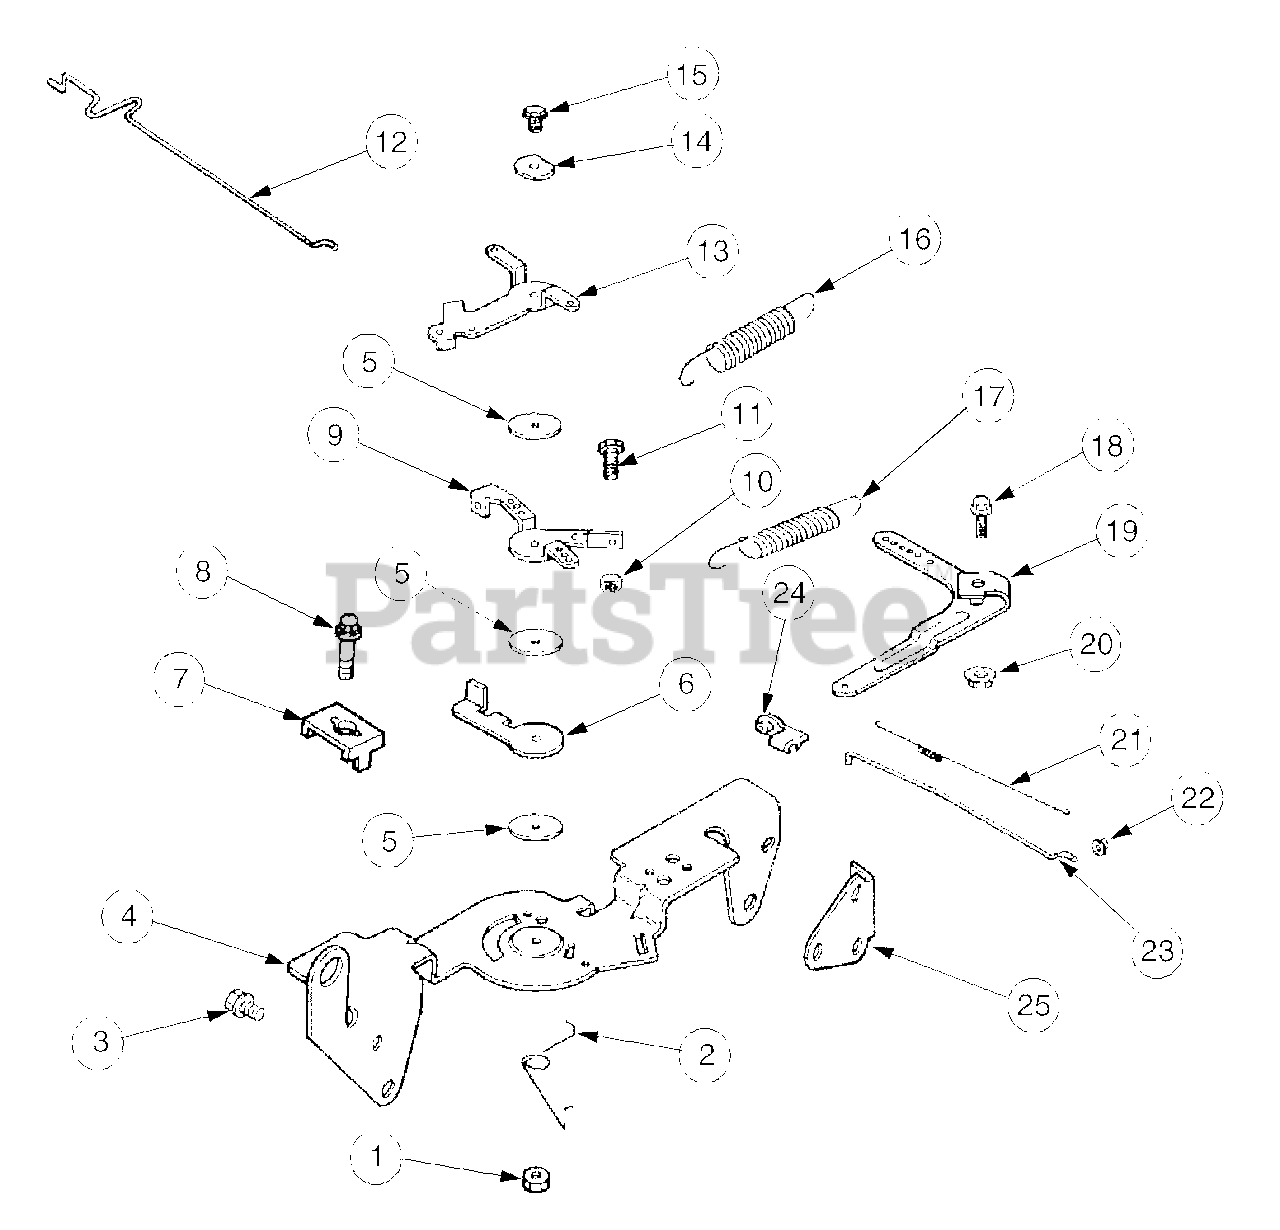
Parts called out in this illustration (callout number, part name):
1	Nut, Hex Lock M5 x 0.8
2	Spring, Choke Return
3	Screw, Hex Flange M6 x 1.0 x 16
4	Bracket, Control
5	Washer, Plain 5.5mm
6	Lever, Throttle Actuator
7	Clamp, Cable
8	Screw, Hex Flange M5 x 0 8 x 16
9	Lever, Throttle Control
10	Nut, Hex M4 x 0.7
11	Screw, Hex Cap M4 x 0.7 x30
12	Linkage, Choke
13	Lever, Choke
14	Washer, Spring 1/4"
15	Screw, Hex Flange M5 x 0,.8 x 20
16	Spring, Throttle Limiter
17	Spring, Governor (6mm)
18	Screw, Hex Flange (6mm)
19	Lever, Governor (6mm)
20	Nut, Hex Flange M6 x 1.0
21	Spring, Linkage
22	Bushing, Linkage Retaining
23	Linkage, Throttle
24	Bushing, Linkage Retaining
25	Bracket, Support
